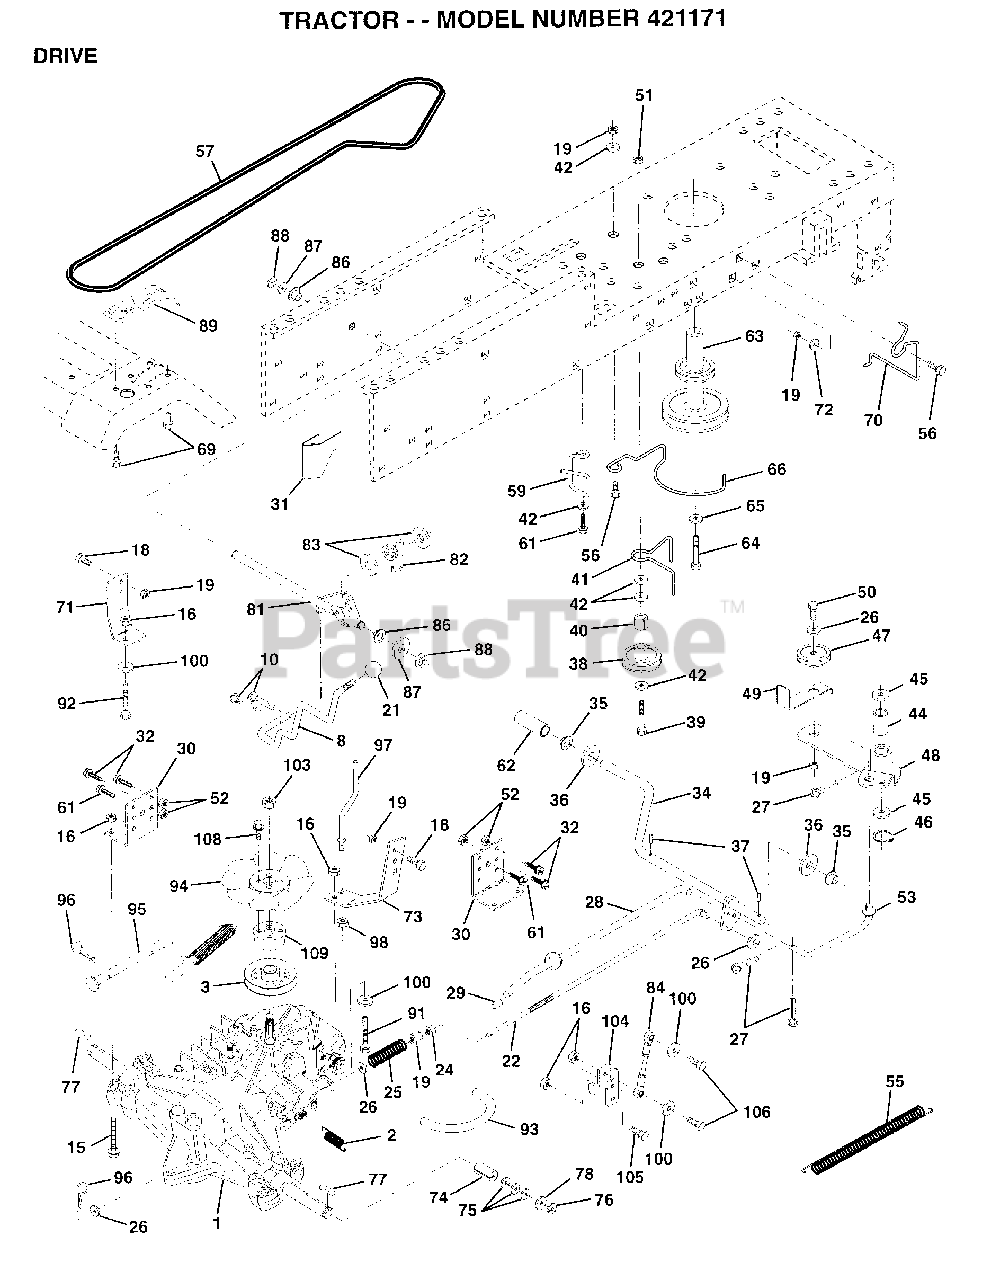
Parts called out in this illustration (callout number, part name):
1	TRANSAXLE ASSEMBLY
2	SPRING RET BRAKE
3	PULLEY.4.20.HYDRO
6	KEEPER.BELT.ENG.L
8	ROD SHIFT FEND LT
10	PIN COTTER 1/8
15	BOLT.HX.FLG.5/16
16	NUT
18	BOLT
19	NUT
21	KNOB DLX BLK/BLK
22	ROD.BRAKE.HYDRO.
24	NUT
25	SPRING ROD LT
26	WASHER
27	COTTER PIN
28	ROD.BRAKE.PARK.LT
29	PLUNGER CAP T
30	TRANSAXLE MTG BKT
31	"KEEPER,BELT LH T"
32	BOLT
34	SHAFT.PEDAL.FOOT
35	NYLON BEARING
36	WASHER LT
38	PULLEY.IDLER.FLAT
39	BOLT
40	SPACER T
41	BELT KEEPER LT
42	WASHER
44	"LY, BEARING"
45	WASHER LT
46	KLIP RING
48	ARM IDLER
49	RETAIN BELT
53	"LINK, CLUTCH T"
55	"SPRING, RETURN LT"
57	BELT-V.HYDR.84.61
59	KEEPER BELT CNTSP
61	SCREW
61	BOLT
62	PEDAL COVER T
63	PULLEY.ENGINE
65	LOCKWASHER
69	SCREW HEXWSH H-L
70	KEEPER BELT ENG
71	STRAP.TORQ.LH.HYD
72	WASHER
73	STRAP.TORQ.RH.HYD
74	SPACER SPLIT
75	WASHER
76	E-RING LT
77	SQUARE KEY
78	WASHER
81	SHAFT.CROSS.HYD
82	"SPRING,TORSION"
83	WASHER
84	ROD.TIE.BALL.HYD.
86	BUSHING
87	WASHER D
88	KLIP RING
92	HEX BOLT
93	"LINE FUEL HYD 4"""
94	"FAN 7"" HYDRO"
96	RETAINER M
97	KEEPER.BELT.RH.HY
98	NUT
100	WASHER M
104	ARM.CONTROL.PUMP
105	SCREW CAP 5/16-18
106	BOLT
108	SCREW.HXHD.10-20
109	ADAPTOR.FAN.HYDRO
